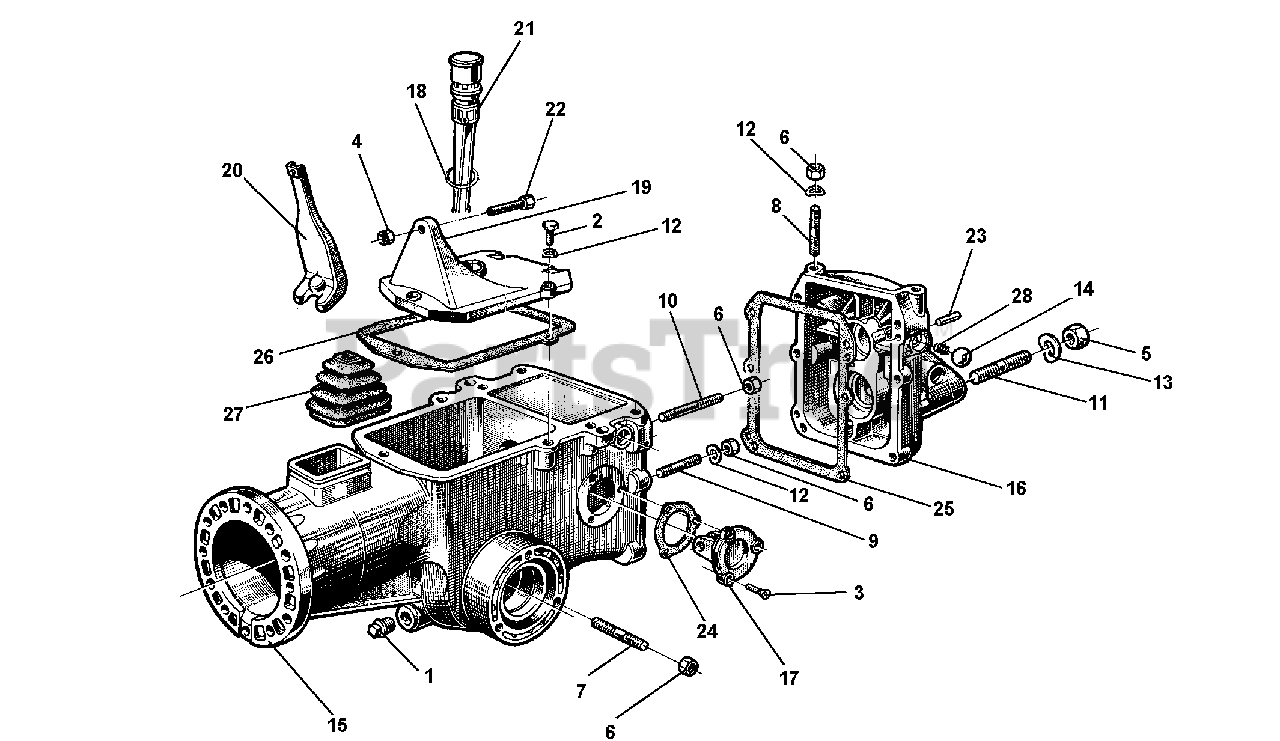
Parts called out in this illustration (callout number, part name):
1	PLUG 1/4 GAS
2	SCREW TE M8 X 25
3	SCREW TSV M6 X 16 UNI 260-5S
5	NUT M12 X 1.25 UNI 5587 6S
6	NUT, SELF LOCKING M8
7	STUD M8 X 46 X 20 X 12
8	STUD M8 X 38 X 14 X 20
9	STUD M8 X 46 X 16 X 16
10	STUD M8 X 58 X 16 X 16
11	ST.56XM12X1.25X26XM12X22 8G
12	WASHER, LOCK 8.4
13	WASHER, LOCK 13
14	BALL 15/32 RIV RB-11.906
15	HOUSING BODY
16	HOUSING COVER
17	REVERSE SPEED FLANGE
18	RUBBER RING
20	CLUTCH LEVER
21	CAP, WITH MEASURING ROD
22	SCREW, ADJUSTING M8
23	PARALLEL PIN D 6 X 20
25	GASKET, COVER
26	GASKET, COVER
